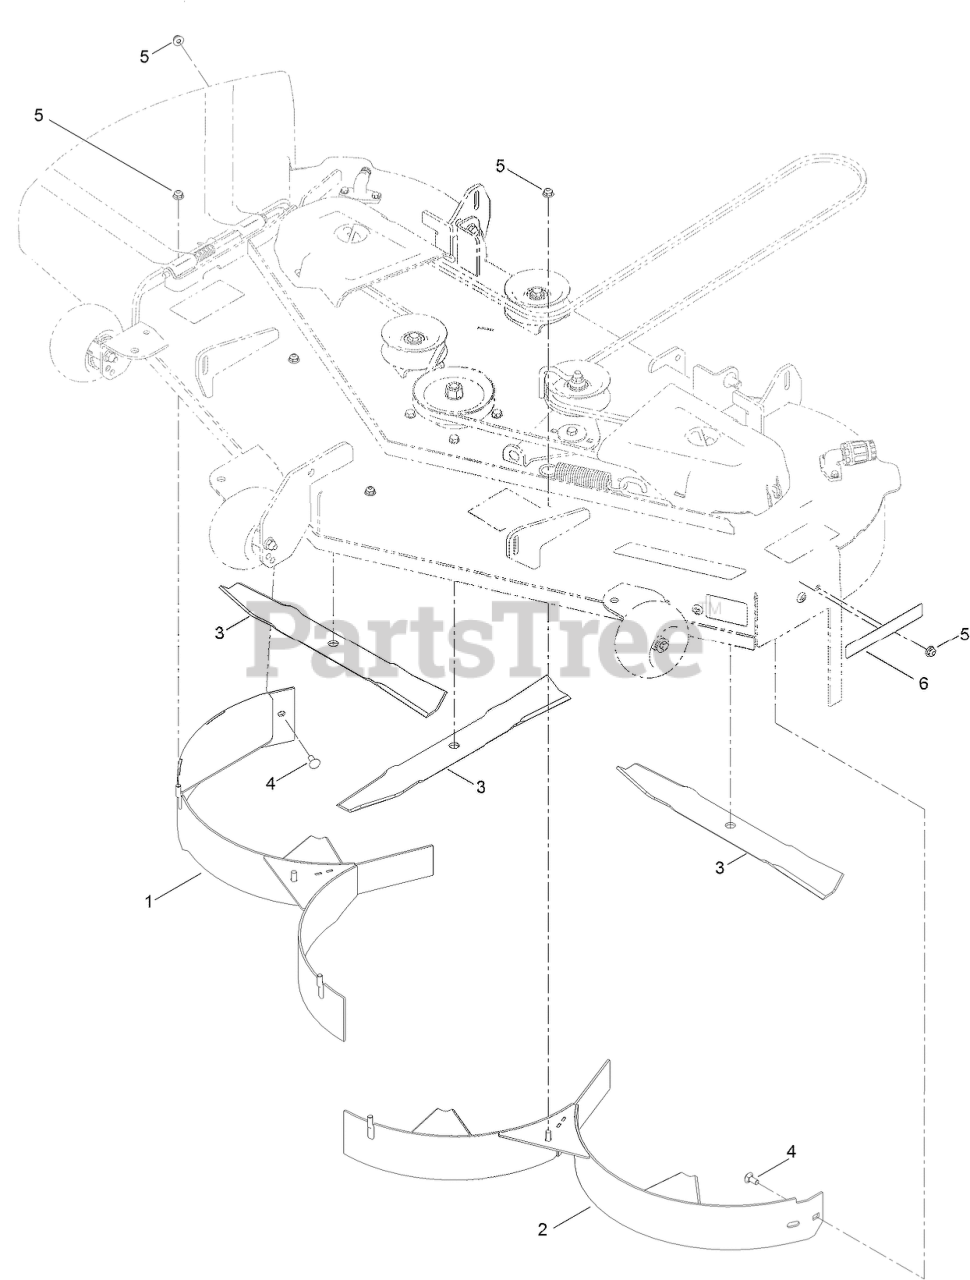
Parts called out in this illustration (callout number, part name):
1	54" BAFFLE ASM (RH)
2	54" BAFFLE ASM (LH)
3	BLADE-MULCH, 18.75 INCH
4	BOLT-CARR
5	NUT-HF
6	DECAL-RECYCLER
